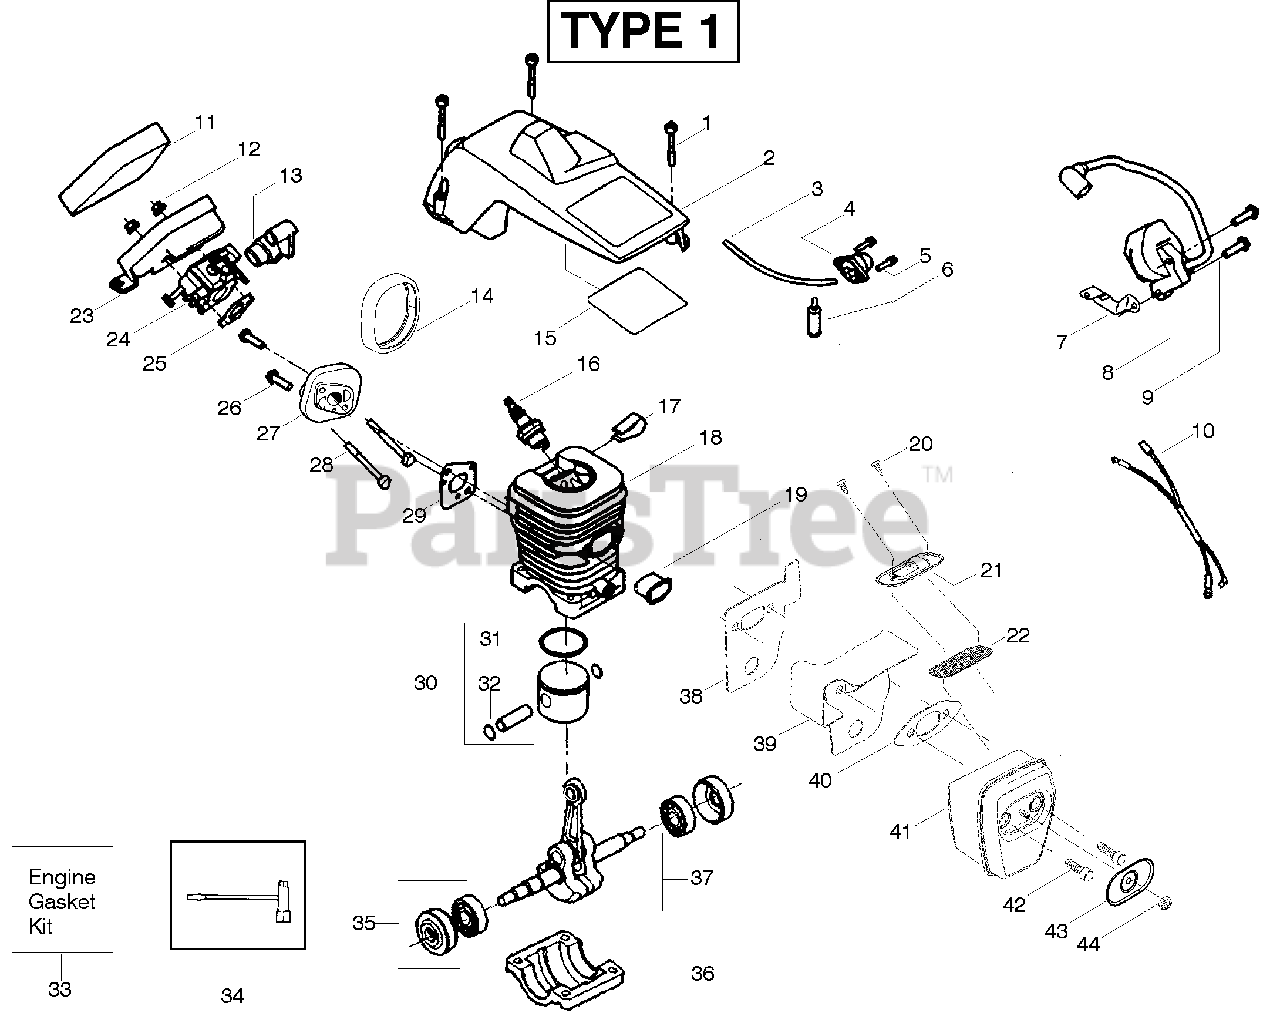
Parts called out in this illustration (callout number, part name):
2	Assy-Cylinder Shield
3	Kit-Fuel Line (Small)
4	Assy- Air Purge
6	Assy-Fuel Pick-up
7	Strap-Ground
8	Ignition Module
10	Assy-Wire Harness
11	Foam- Air Filter
13	Grommet-Carb Adjust
14	Seal-Carb Adapter
15	Reflector-Heat
16	Spark Plug (RCJ-7Y)
17	Clip-High Tension Lead
18	Kit-Cylinder
19	Insulator-Heat
20	Screw-Outlet cover
21	Cover - Outlet
22	Kit-Spark Arrestor
23	Air Filter Housing
24	Kit-Carburetor (WT-599)
24	Kit-Carburetor (W-9A)
25	Gasket-Carb.
27	Carb. Adapter
29	Gasket-Carb Adaptor
30	Kit-Piston
31	Ring-Piston
32	Retainer-Piston Pin
33	Kit-Engine Gasket
34	Bar Wrench
35	Assy-Seal & Bearing
36	Cap-Crankcase
37	Assy-Crankshaft
38	Backplate
39	Guide-Outlet
40	Gasket-Muffler
41	Assy-Muffler
42	Bolt-Muffler
43	Cover-Bolt
44	Nut-Brass
